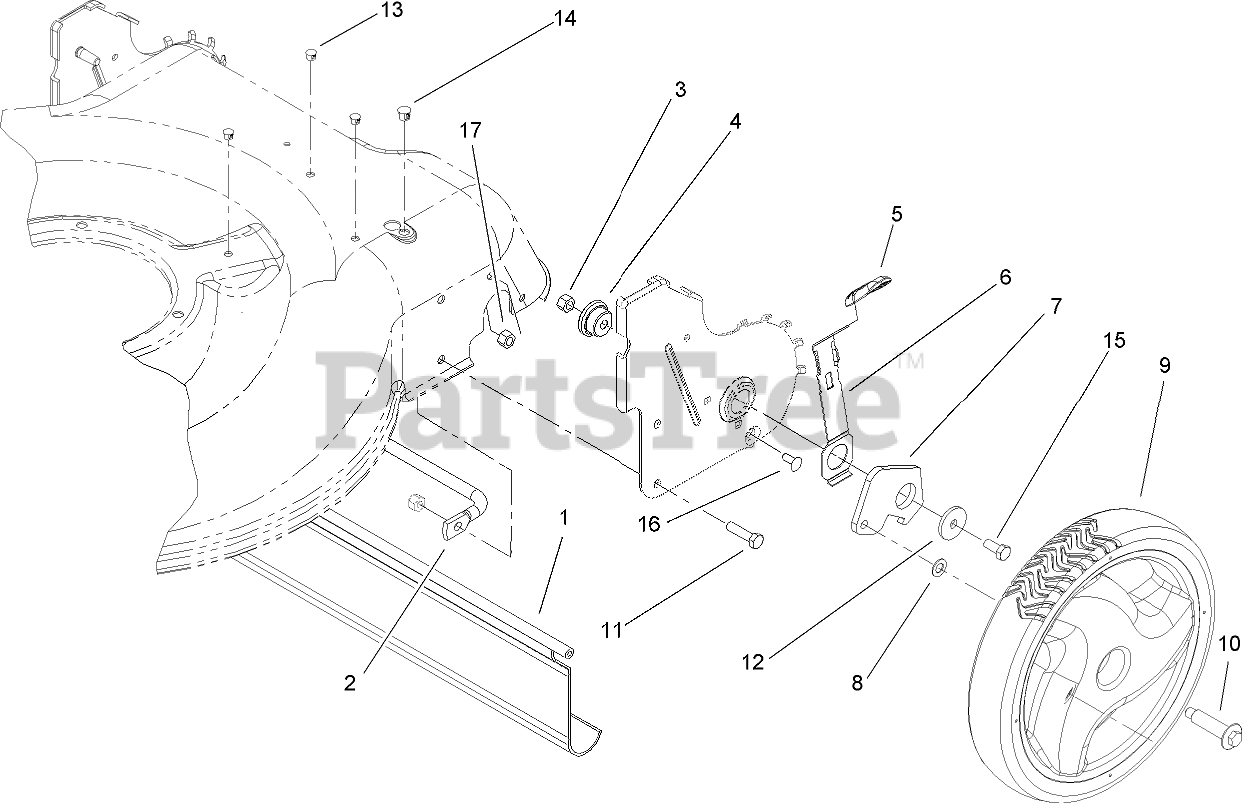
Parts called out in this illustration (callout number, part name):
1	Shield-Trailing
2	BRACE-PLATE, HOC
3	NUT-HEX, SIDE DEFORM
4	BUSHING-MOUNT
5	Knob-Lever, HOC
6	ARM-11 INCH SPRING, REAR
7	Arm-Pivot, Rear (LH)
8	WASHER-BOLT, WHEEL
9	11 INCH WHEEL ASM
10	BOLT-SHOULDER
11	SCREW-HH
12	Washer-Flat
13	Plug-Dome
14	Plug-Dome
15	SCREW-HH
16	SCREW-CARR
17	NUT-LOCK, NI
